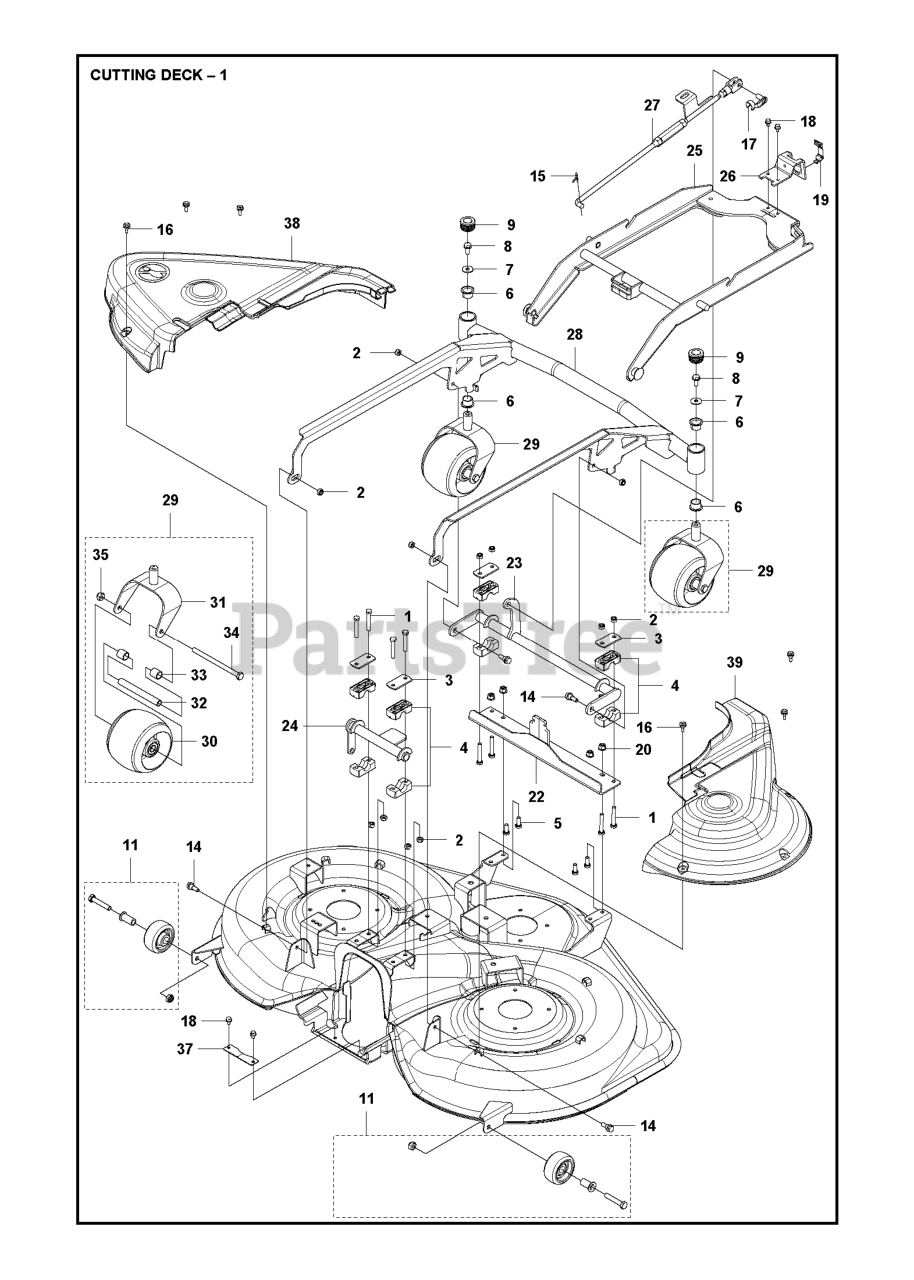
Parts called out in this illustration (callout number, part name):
2	LOCKNUT M8
19	CLIP GRAY
20	NUT FLANGE
29	PIVOT WHEEL ASSY
30	DECK ROLLER, FRONT
35	NUT
